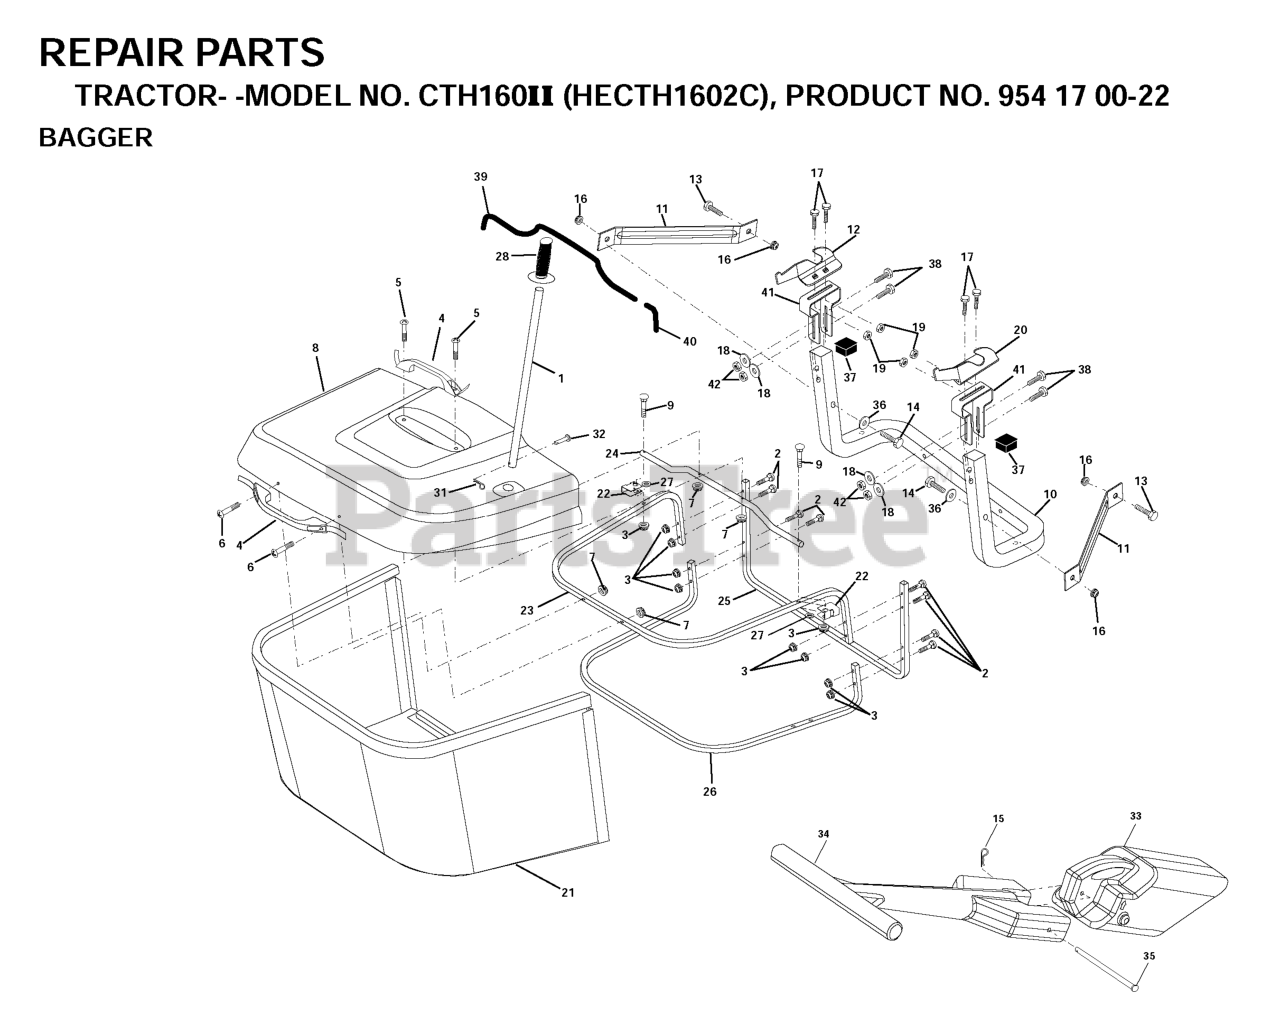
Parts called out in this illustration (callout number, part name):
1	TUBE HANDLE BAGGER
2	Bolt Carriage 1/4-20 x 2.0 Gr.5
3	NUT T
4	HANDLE.BAGGER.W/LVRS.BLK.CRD
5	SCREW.PAN.HEAD
6	REPL BY 532 75 00-29
8	COVER
9	Bolt Carriage 1/4-20 x 2.25d x Gr.5
10	TUBE
11	BRACKET.SUPPORT.UPPER.BAG.CRD
14	Bolt Hex 3/8-16 x 2-1/2 Gr. 5
15	RETAINER-SPRNG RB
16	NUT LOCK FLG 3/8-16 UNC
17	RP BOLT 5/16-18 X3/4 ZN/YEL GR
18	WASHER M
19	NUT LOCK HEX FLANGE 5/16-18
20	BRACKET
21	BAG
22	BRKT.SIDE.BAG.CRD
23	TUBE.UPPER.BAG.CRD
24	TUBE.PIVOT.BAG.CRD.BLACK
26	TUBE.LOWER.BAG.CRD
28	Grip Handle Black
31	RETAINER M
32	RIVET,DRILLED
33	MULCH PLUG, CTH150
34	HANDLE.MULCHER.92.CRD (2 2)
36	WASHER
37	Plug Support Bagger CRD
38	BOLT.5/16-18X2.5
39	TRIM
40	TRIM
41	BRKT.VERT.ADJ.BAGGER.CRD
42	NUT.71038.31-18.HEX.NYLOCK
